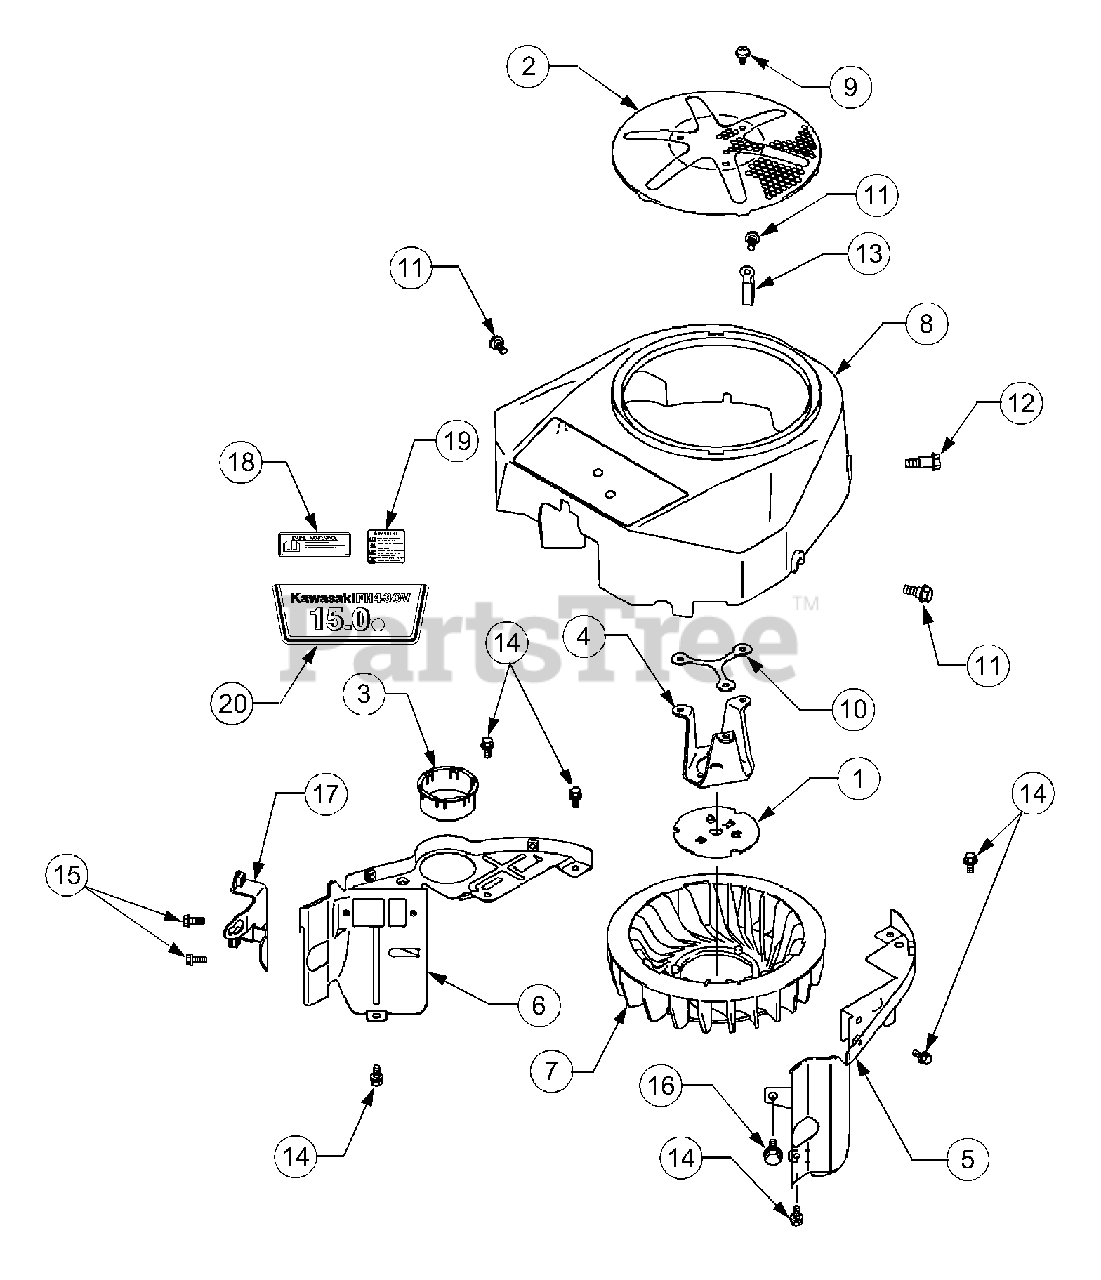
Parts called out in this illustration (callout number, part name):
2	Screen
4	Bracket, Comp
5	Shroud, Engine, #2 Cylinder
6	Shroud, Engine
7	Fan
9	Screw, 6x10
12	Bolt
14	Bolt, Flanged
15	Bolt, Flanged
16	Bolt, Flanged
17	Bracket
18	Label, Manual
19	Label, Warning
20	Label, Brand
